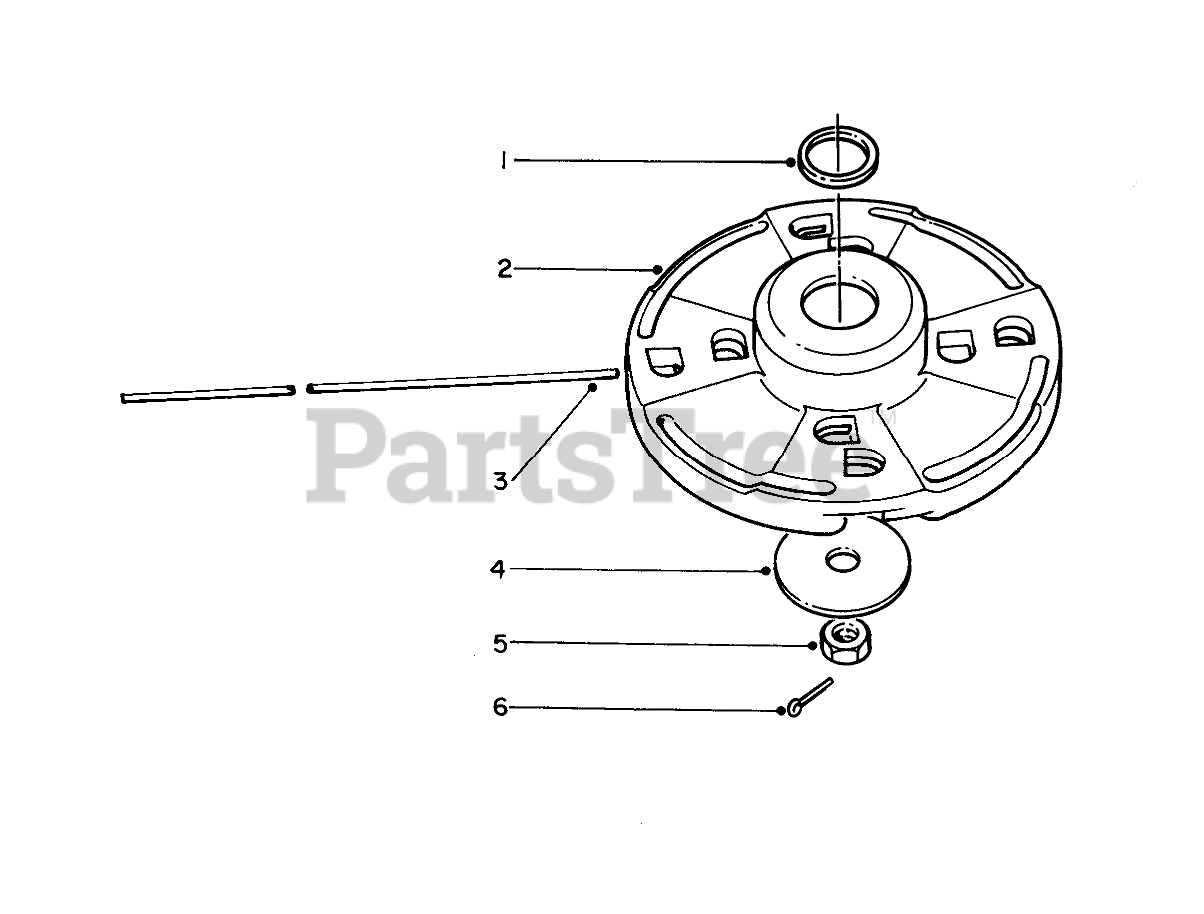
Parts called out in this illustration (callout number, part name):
1	SPACER
2	Cutter Head (Incl. Ref. #1)
3	Filament Line Pkg. (24 Pcs.)
4	WASHER
6	Split Pin
